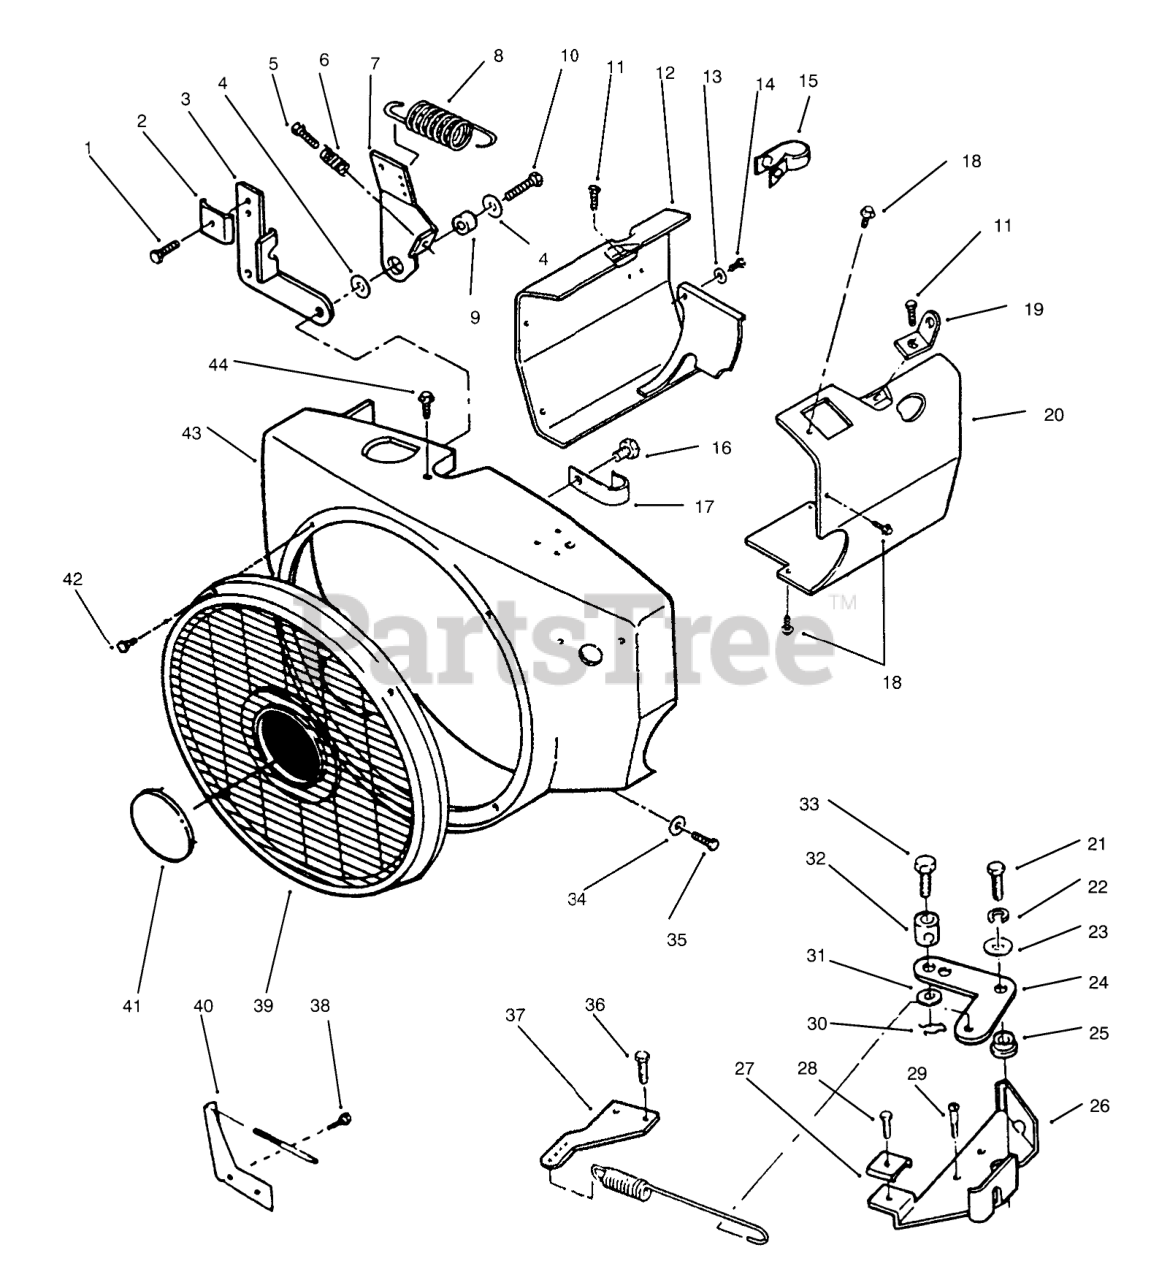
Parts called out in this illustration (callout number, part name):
1	SCREW-TAPPING
3	Bracket
4	WASHER-FLAT
5	SCREW-TAP
6	SPRING
7	GOVERNOR-CONT ARM
8	SPRING
9	BUSHING
11	SCREW-HWH
12	LH AIR CYLINDER HSG
13	WASHER-FLAT
14	SCREW-HH
15	WIRE CLAMP
16	SCREW-HWH
17	CLIP-WIRE
18	SCREW-HWH
19	BRACKET-LIFTING
20	RH AIR CYLINDER HSG
21	SCREW - CAP HEX HEAD
22	WASHER-LOCK, SPRING
23	WASHER-FLAT
24	Governor Control Arm
25	BUSHING-GOV CONTROL
26	BRKT-GOVERNOR CONTRL
28	SCREW-HWH
29	HEX HD CAP SCREW
30	PIN-COTTER
31	Washer
32	BUSHING
33	SCREW
34	WASHER-FLAT
35	SCREW-HH
36	SCREW-TAPPING PAN HD
37	ADAPTER-GOV ARM
38	SCREW-HWH
39	GUARD-STATIONARY
40	BRACKET
41	NAME-PLATE TORO LOGO
42	SCREW-PAN HEAD
43	BLOWER-HOUSING
44	HEX HD CAPSCREW
